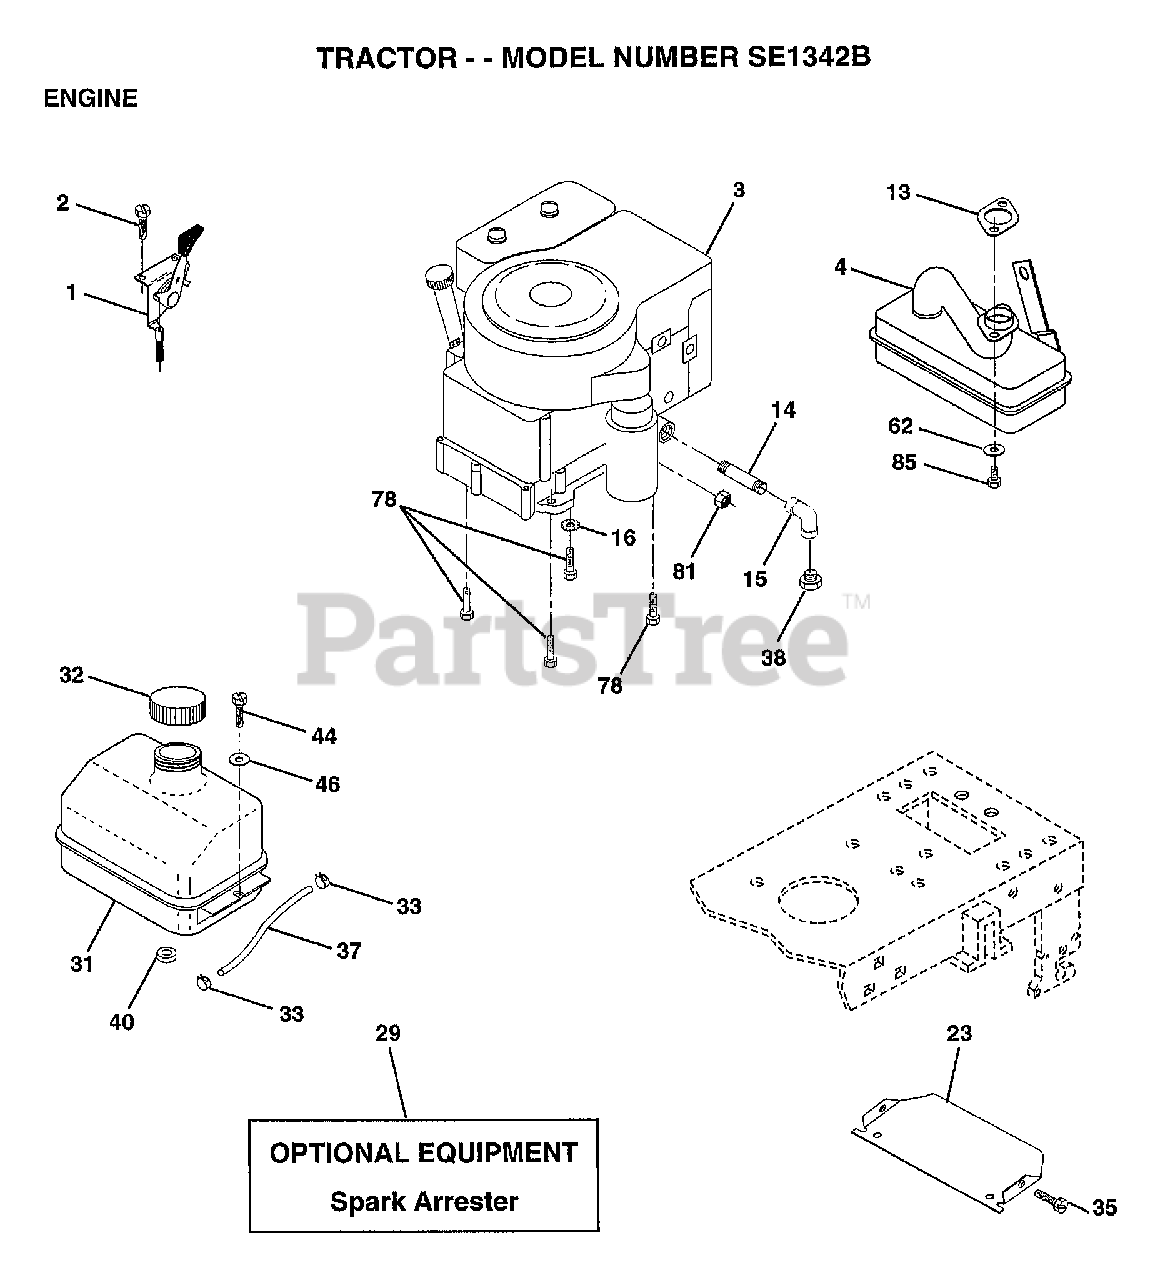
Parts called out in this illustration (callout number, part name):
1	CONTROL-THROT/CHO
2	SCREW LT
4	MUFFLER TEC. 13HP
13	GASKET ENG 1 313 LD TIN PLATED
14	PIPE NIPPLE LT
15	ELBOW
16	LOCKWASHER
23	SHIELD-HEAT
31	TANK.FUEL.LT.
32	CAP ASM FUEL
33	HOSE CLAMP
35	SCREW
37	LINE FUEL
44	SCREW HEX CRT
46	WASHER
62	LOCKWASHER
78	SCREW
81	NUT
85	SCREW HEX HD CAP
